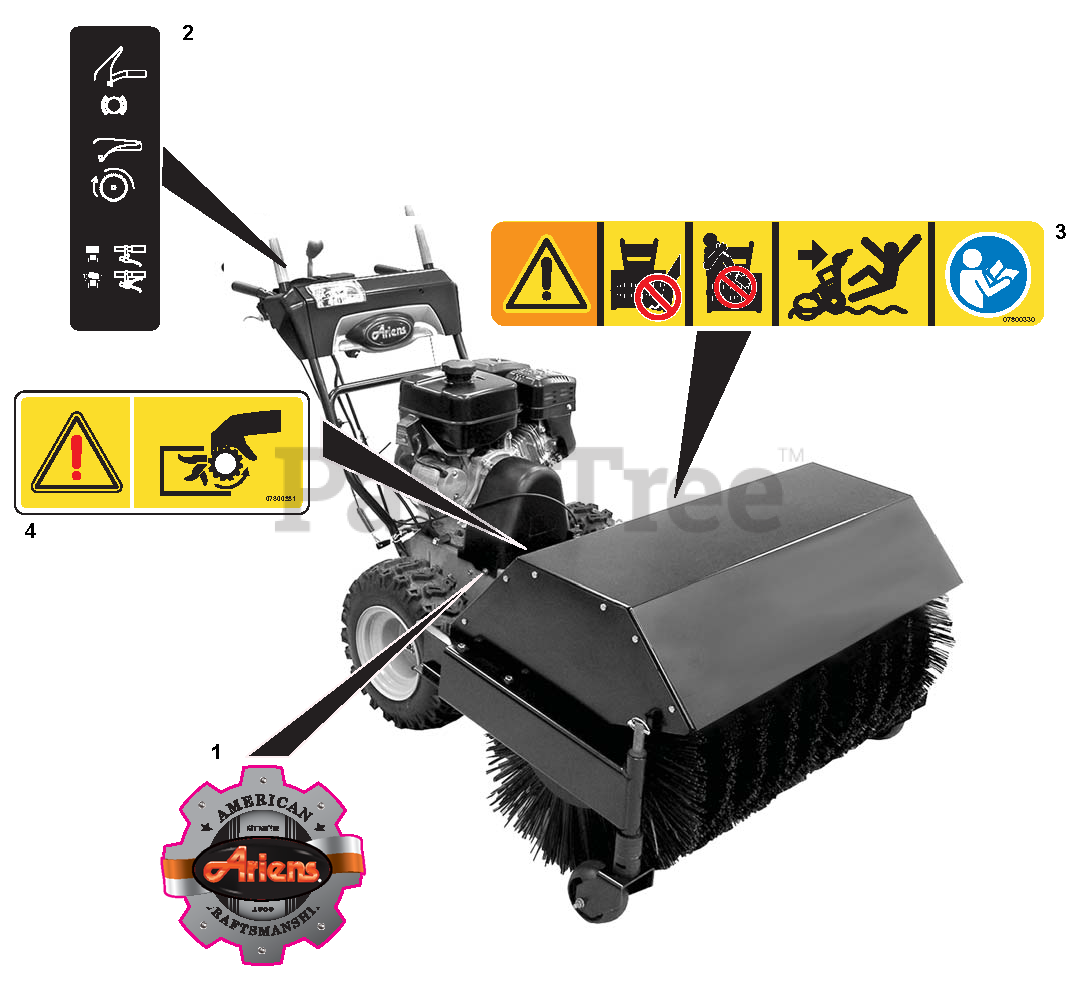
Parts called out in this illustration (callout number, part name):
1	Decal, Ariens Heritage - Large
2	DECAL, CONTROL-BRUSH ANGLE
3	DECAL, DANGER -POWER BRUSH-CE
4	DECAL, PTO WARNING
